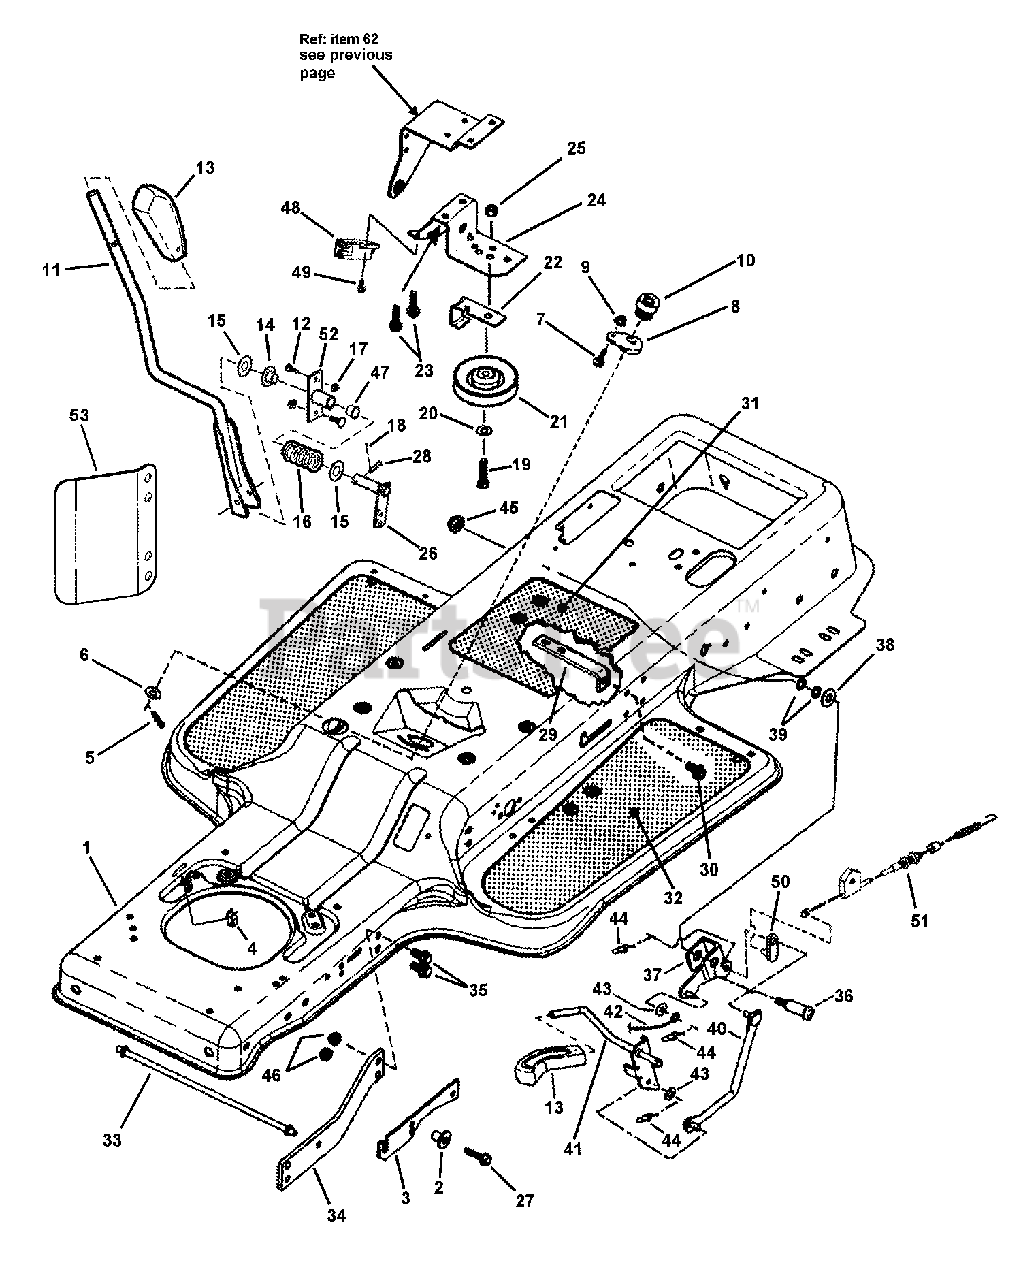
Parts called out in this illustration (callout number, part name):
1	FRAME, Tractor (I piece)
2	BUSHING, Flange
3	BRACKET, Hood Pivot
4	WIRE CLIP, .28 x .41
5	PIN, 1/8 x 3/4" Cotter
6	SHIM WASHER, .50 x .75 x .03
7	BOLT, 1/4-20 x 5/8" Short Neck Carriage, GR 5
8	ASSEMBLY, Steering Adjuster
9	NUT, 1/4-20 Hex Flange Lock
10	GEAR, Pinion, Steering
11	WELDMENT, Shift Handle- TTK46
12	BOLT, 5/16-18 x 3/4" Short Neck Carriage, GR 5
13	LEVER Shift Handle
14	BUSHING, 3/4 - 1.62 Flange
15	THRUST WASHER
16	SPRING, Shift Detent
17	NUT, 5/16-18 Hex Flange Lock, GR 5
18	PIN, 3/32 x 3/4" Cotter
19	SCREW, 3/8-16 x 1-1/2" Hex Head Cap, GR 5
20	WASHER, 3/8" Flat
21	PULLEY, Idler V, 3.30 HA
22	BELT GUIDE, 3-1/2" Dia.
23	SCREW, 5/16-18 x 1-1/4" Swage
24	SUPPORT, PTO Lever
25	NUT, 3/8-16 Hex Center Lock, GR 5 or B
26	WELDMENT, Arm
27	SCREW, 5/16-18 x 1-1/4" Hex Head Self-Tap
28	PIN, 1/4 x 1-5/8" Clevis
29	ANCHOR, Blade Brake
30	SCREW, 3/8-16 x 5/8" Hex Washer Self-Tap
31	DECAL, Instruction Frame Top
31	DECAL, Instruction Frame Top (Euro)
32	FOOT PAD, Textured (Black)
33	BELT GUIDE
34	BRACE, Frame
35	BOLT, 3/8-16 x 3/4" Hex Flange Lock
36	BOLT, 1/2-13 Shoulder
37	WELDMENT, Bellcrank PTO
38	THRUST WASHER
39	WASHER, 1/2" Internal Tooth Lock
40	WELDMENT, PTO Link
41	WELDMENT, PTO Lever
42	CABLE, 33 Blade
42	CABLE, PTO
43	WASHER, 7/16" Flat SAE
44	PIN, 3/8 Self Lock Cotter
45	NUT, 1/2-13 Hex Flange Lock
46	NUT, 3/8-16 Hex Flange Lock
47	BUSHING, 3/4 - I" Flange (nylon)
48	SWITCH- DPDT NC/NO
49	SCREW, #10-32 x 5/8" Hex Washer Head Machine, GR 5
50	WELDMENT, Bracket
51	ASSEMBLY, Cable (part no. stamped on cable)
52	WELDMENT, Pivot Plate
53	HEAT SHIELD (Foot Rest)
